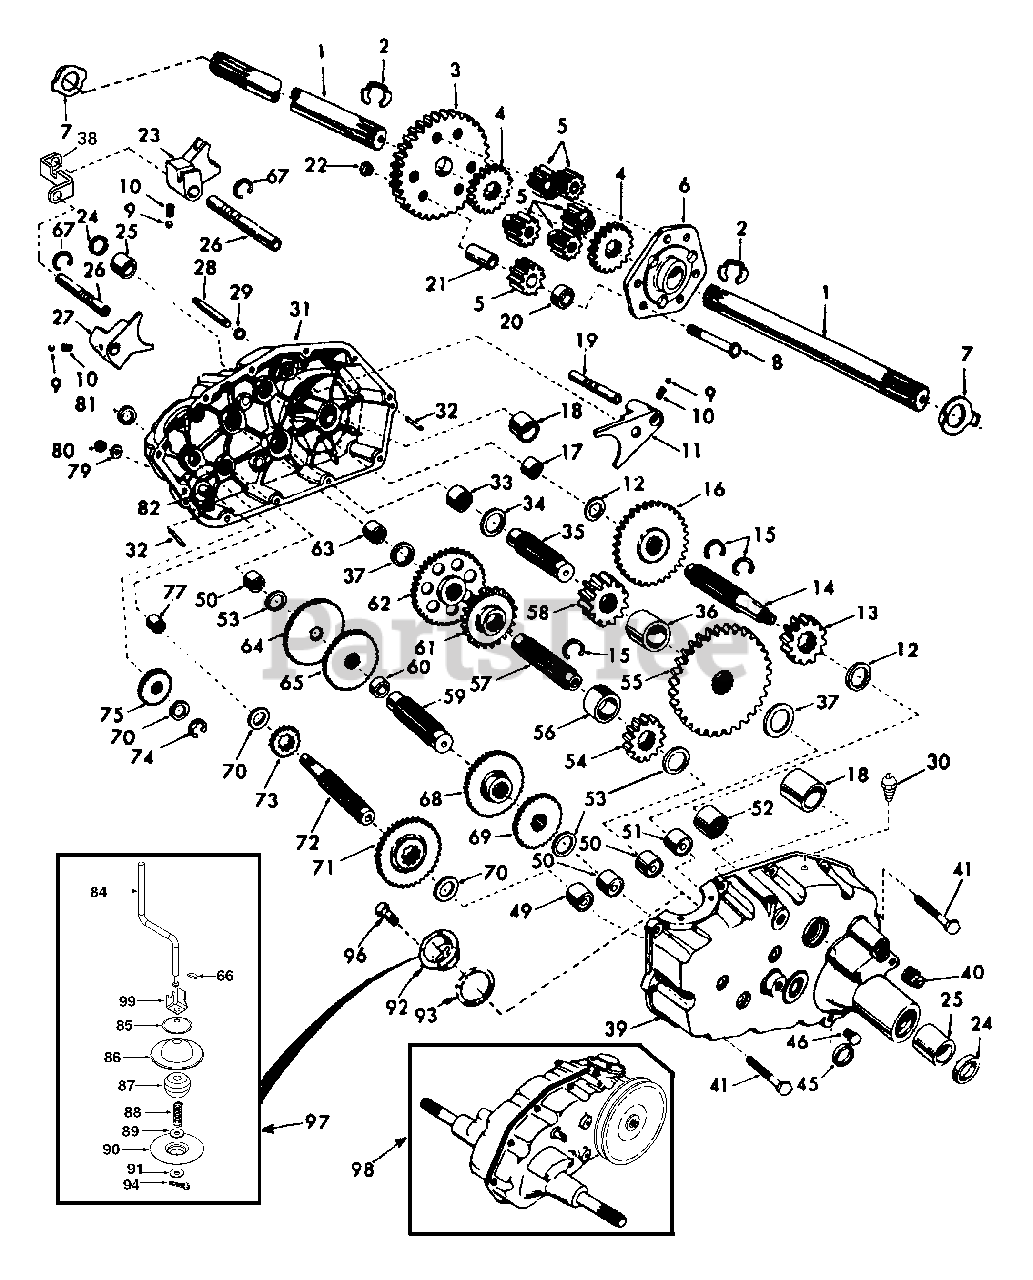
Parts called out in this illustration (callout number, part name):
2	Retaining Ring
3	Final Drive Gear
4	Differential Gear
5	Differential Pinion
6	Differential Carrier
7	Axle Thrust Washer
8	Bolt, Hex Head 3/8-24 x 3-1/4 (1" Thread Length)
9	Steel Ball
10	Spring Shift Fork Detent
11	Shift Fork, High-Low Range
12	Thrust Bearing Race
13	4th Reduction Pinion
14	Shaft, Brake
15	Snap Ring, Crescent Type
16	High-Low Range Gears
17	Needle Bearing
18	Sintered Iron Bearing
19	Shift Fork Shaft, High-Low Range
20	Differential Pinion Spacer
21	Differential Pinion Bushing
22	Gripco Centerlock Nut 3/8-24
23	Shift Fork, R.H.
24	Oil Seal
25	Sintered Iron Bearing
26	Shift Fork Shaft
27	Shift Fork, L.H.
28	Shift Shaft, High-Low Range
29	Oil Seal
30	Pressure Relief Valve
31	Gearcase, Reverse Idler Shaft and Bearings, R.H.
32	Dowel Pin
33	Needle Bearing
34	Thrust Bearing Race
35	4th Reduction Gear Shaft
36	4th Reduction Gear Spacer
37	Thrust Bearing Race
38	Gate, Lower, Shift
39	Gearcase and Bearings, L.H.
40	Pipe Plug 1/2-14 N.P.T.
41	Bolt, Hex 5/16-18 UNC x 1-1/4
45	Oil Seal
46	Pipe Plug 1/4-18 N.P.T.
49	Needle Bearing
50	Needle Bearing
51	Needle Bearing
52	Needle Bearing
53	Thrust Bearing Race
54	3rd Reduction Pinion, Low
55	4th Reduction Gear
56	3rd Reduction Pinion Spacer
57	2nd Reduction Gear Shaft
58	Final Drive Pinion
59	1st Reduction Gear Shaft
60	1st Reduction Shaft Spacer
61	3rd Reduction Pinion High
62	2nd Reduction Gear
63	Needle Bearing
64	Low Speed Gear and 2nd Reduction Pinion Cluster
65	Reverse Gear
66	Key, Hi-Pro
67	Klip Ring
68	Intermediate Speed Gear
69	High Speed Gear
70	Thrust Bearing Race
71	Intermediate and High Speed Cluster Pinions
72	Input Shaft
73	Low Speed Pinion
74	E-Ring
75	Reverse Idler Gear
77	Needle Bearing
79	Sealing Washer
80	Nut, Hex, Jam 7/16-20
81	Oil Seal
82	Reverse Idler Shaft
84	Gearshift Lever, Bent
85	Gearshift Cap
86	Gearshift Ball Cover and Pin
87	Shift Lever Guide Ball, Keyed
88	Spring
89	Washer
90	Shift Mechanism Seal
91	Washer
92	Gearshift Gate and Reinforcement
93	Shift Ball Cover Gasket
94	Cotter Pin 1/8 x 3/4
96	Bolt, Hex, 5/16-18X1 Epoxy Patch
97	Lever Assembly, Gearshift
98	Transaxle, 6 Speed, Complete Assembly
99	Actuator, Shift Lever
